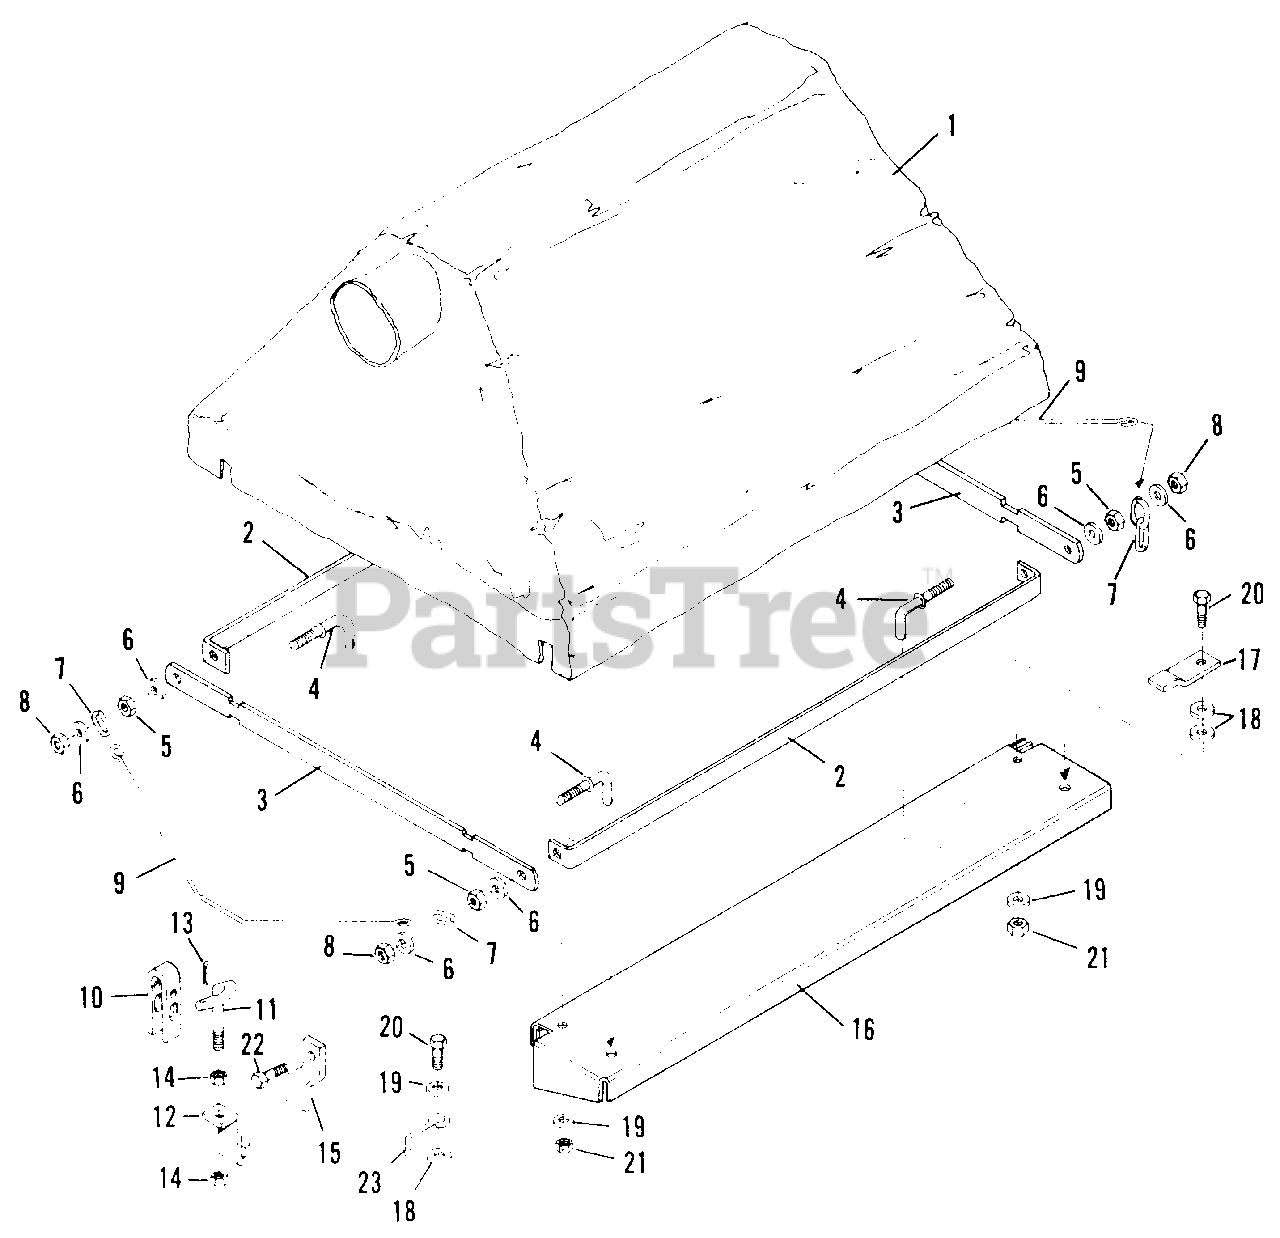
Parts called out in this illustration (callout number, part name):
2	Side Bar Reinf.
3	End Bar Reinf.
5	Hex Nut, 3/8-16
6	Flat Washer, 3/8
8	Hex Nut, Centerlock
11	Rod Latch
13	Cotter Pin
14	Hex Nut Centerlock
15	Bracket
16	Side Panel
18	Washer, Special
19	Plain Washer, 5/16
20	Hex Capscrew, 5/16-18 x 3/4
21	Hex Locknut, 5/16-18
22	Hex Capscrew, 3/8-16 x 1-1/4
23	Belt Stop
